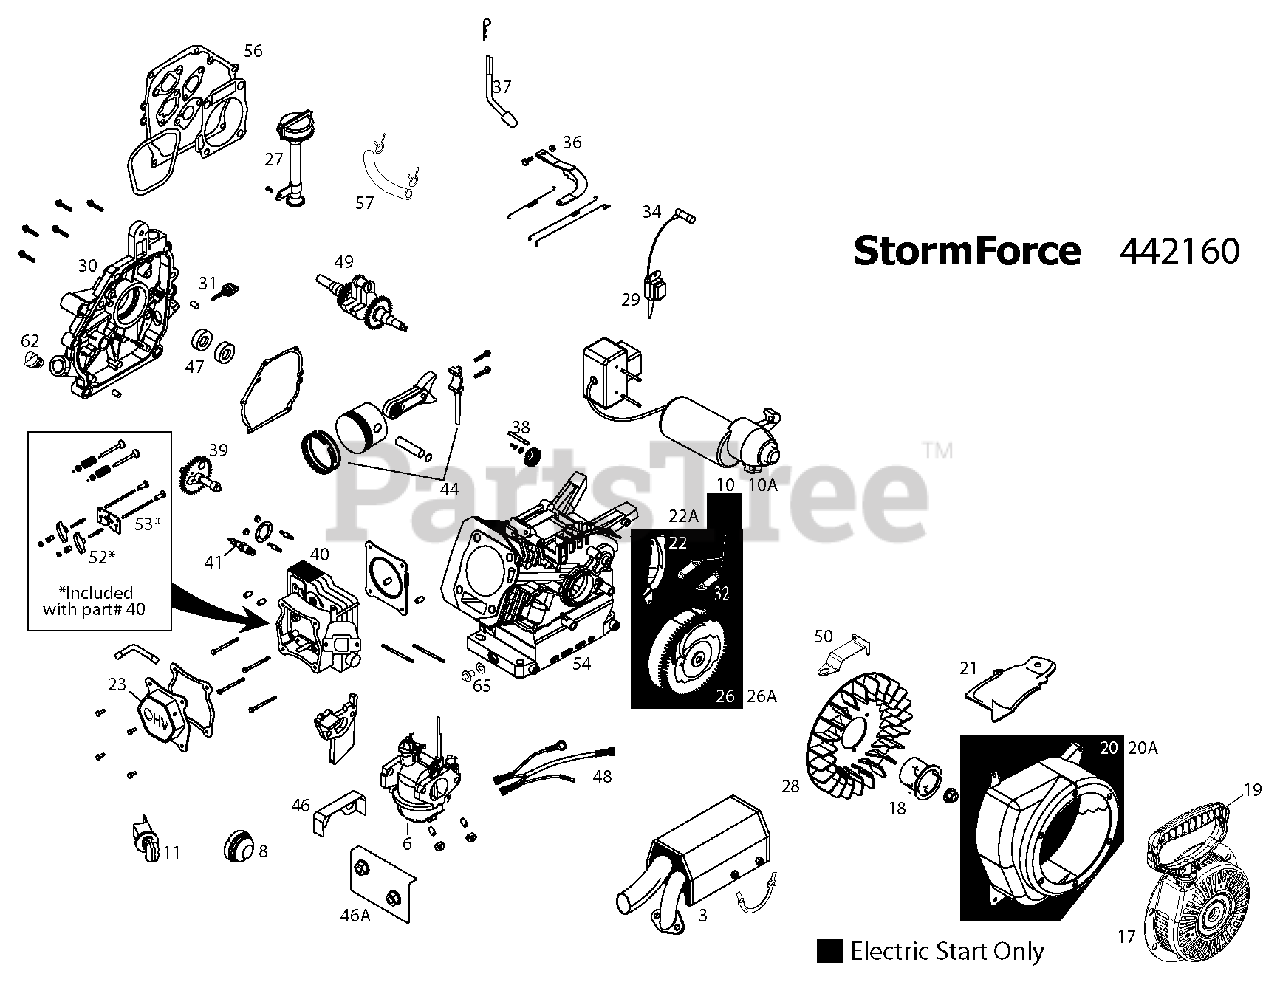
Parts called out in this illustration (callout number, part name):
3	MUFFLER.ASM.LCT.208CC.SNGL.STG
6	CARB.ASM.SS/SNO.LCT(SKSNO313)
8	BULB.FUEL.PRMR.W/HOSE(SKSNO306
10	STARTER.ASM.ELEC.(SKSNO411)
10A	STARTER STARTER.EURO
11	SWITH.KEY.ASSEM.SNOW.SINGLE.ST
17	RECOIL.STRT.ROUND(BLK) SNOW
18	STRTER.CUP(NON-SLOT)SKSN0601.2
19	HANDLE.RECOIL.DELUXE.LCT
20	BLOW.HSG.ASSY.ELECSKS
20A	BLOW.HSG.ASSY.ELEC(SKSN-0612)
21	SHILED.FLYWEEL.SYS(SKSN-0604)
22	SHLD.ELEC.START.FLY(SKSN-0605)
22A	SHIELD.FLYWEEL.MAN(SKSN-0607)
23	VALVE COVER ASSEMBLY
26	FLYWHL.ASSY.ELECT.(SKSN0405)
26A	RP KIT.FLYWHEEL.SERVICE
27	HIGH OIL-FILL TUBE ASSY
28	KIT.COOLNG.FAN.SERV(SK208-4000
29	COIL.ING.CDI.HI TEMP.SKSNO416.
30	CRANKCASE COVER ASSY
31	DIPSTICK SMALL
32	CHARGING.COILS.18-WATT
34	SPARK.PLUG.BOOT.SNW,SKSN4691.1
36	KIT.GOVERNOR.ARM(SUMMER ENG)
37	KIT.GOVERNOR.CRANK(SK208-3100)
38	GOVENOR.GEARS ASM(SK2082900)
39	KIT.CAMSHAFT.208CC.LCT
40	CYLINDR.HEAD.SRV.KIT
41	SPARK.PLUG(2083810)
44	KIT.PISTON.SRV(SK208-1400)
46	SHIELD.VAPOR.SNOW
46A	SHIELD.INTAKE.(LCT.SKSN0140.1)
47	SEAL KIT (2 PCS)
48	HARNESS.WIRE.SINGLE.STAGE.LCT
49	CRANKSHAFT-KEYED(SK2081800.1)
50	SPEED.CTRL.BRKT.(SKSN0150)
52	ROCKER ARM KIT
53	KIT.PUSH.ROD.SRV(SK208-1001)
54	CYLINDER.ASM.SKSN0001.2
56	GASKET.KIT.208CC(SK2084300.1)
57	KIT.FUEL.HOSE.208CC.SING/STAGE
62	NON REMOVABLE PLUG
65	KIT.OIL.DRAIN.PLUG(SK2089911
